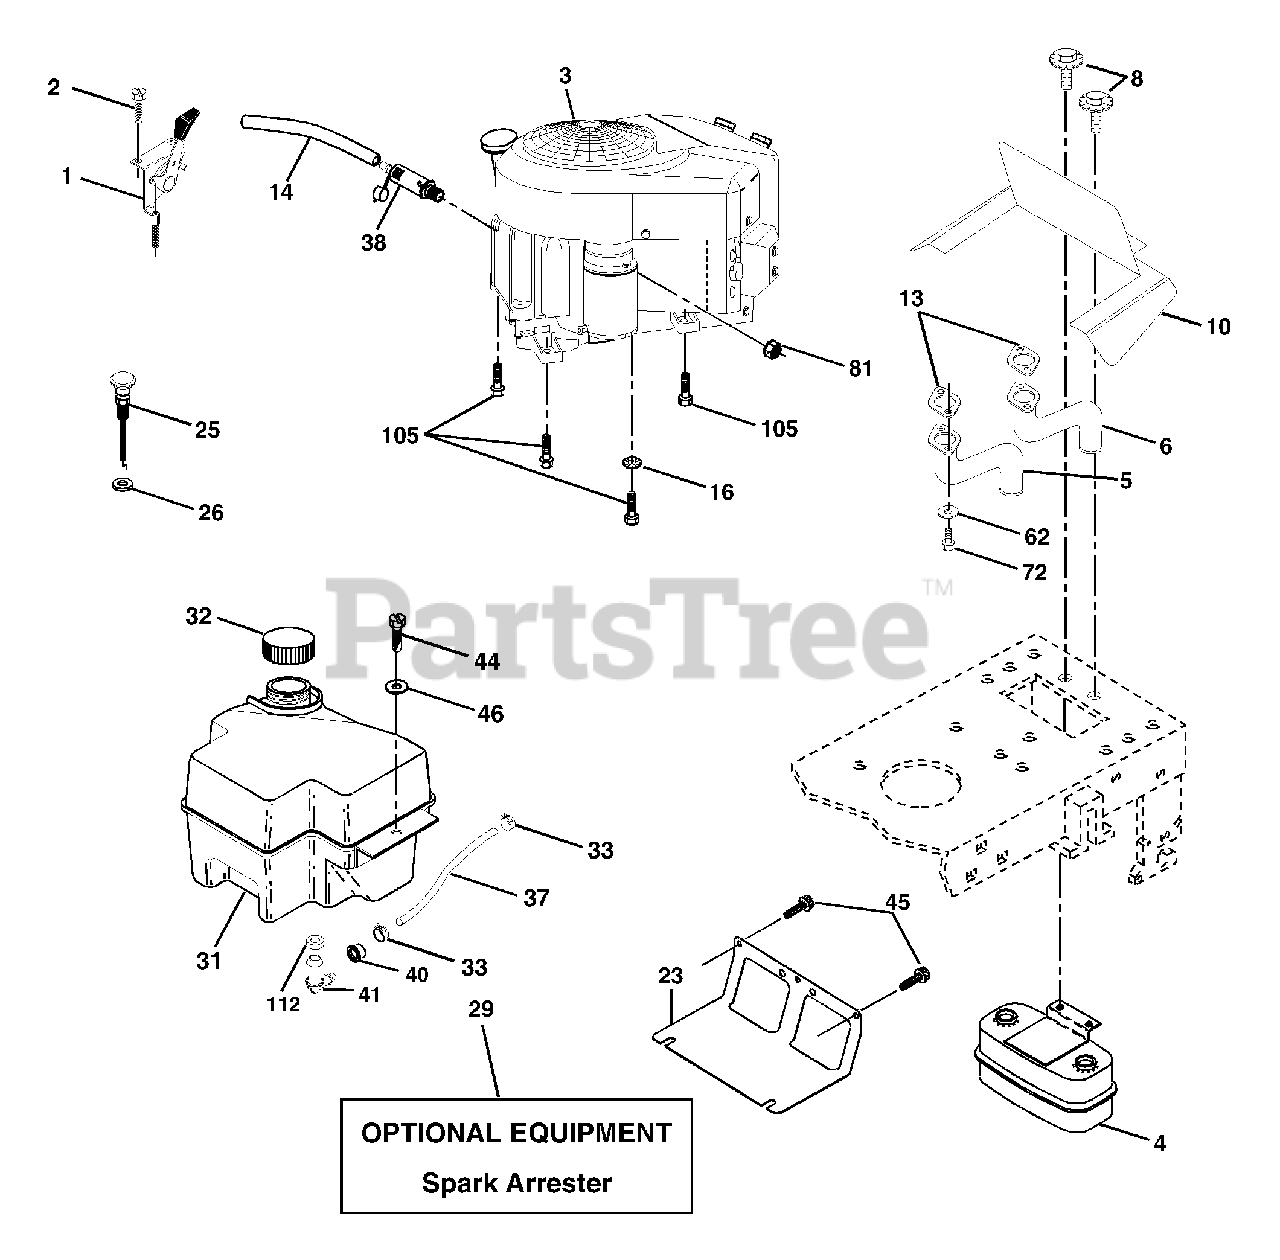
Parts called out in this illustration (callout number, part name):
1	Control Throt /Ch Flag
2	Screw Hex Thd Cut 1/4-20x1/2
4	Muffler
5	Exhaust Tube LH
6	Exhaust Tube RH
8	Bolt 5/16-18unc x 3/4
10	Shield Muffler
13	Gasket
14	Tube Drain Oil Easy
16	Washer Lock Ext Tooth 3/8
23	Shield Browning/Debris Guard
25	Control Choke
26	Nut Keps 3/8-24 Unf
29	Arrestor Spark
31	Tank Fuel
32	Cap Asm Fuel W/sym Vented
33	Clamp Hose Blk
37	Line Fuel 20"
38	Plug Drain Oil Easy
40	Bushing Snap
41	Stem Fuel Tank
44	Screw Hexwsh Thdrol 1/4-20x3/4
45	Screw Hex Wsh Thdrol 3/8-16
46	Washer 9/32 X 7/8 X 16ga
62	Washer Lock 5/16
72	Screw Hex Hd Cap 5/16-18 x 3/4
81	Nut Keps Hex 1/4-20 Unc
105	Screw Thdrol 3/8-16x1-1
112	Bushing, Outlet
